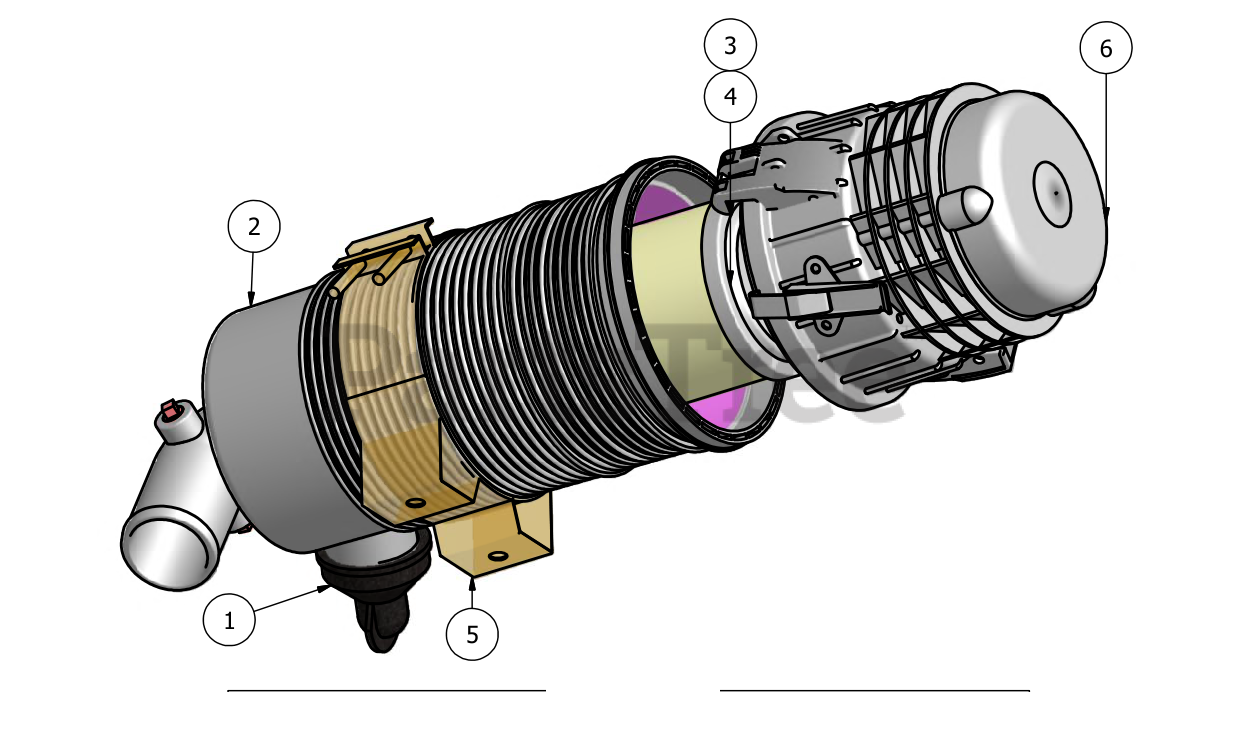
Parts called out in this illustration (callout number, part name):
1	Debris Plug
2	Canister Body
3	Inner Filter
4	Outer Filter
5	Mounting Bracket
6	Diesel Air Filter
